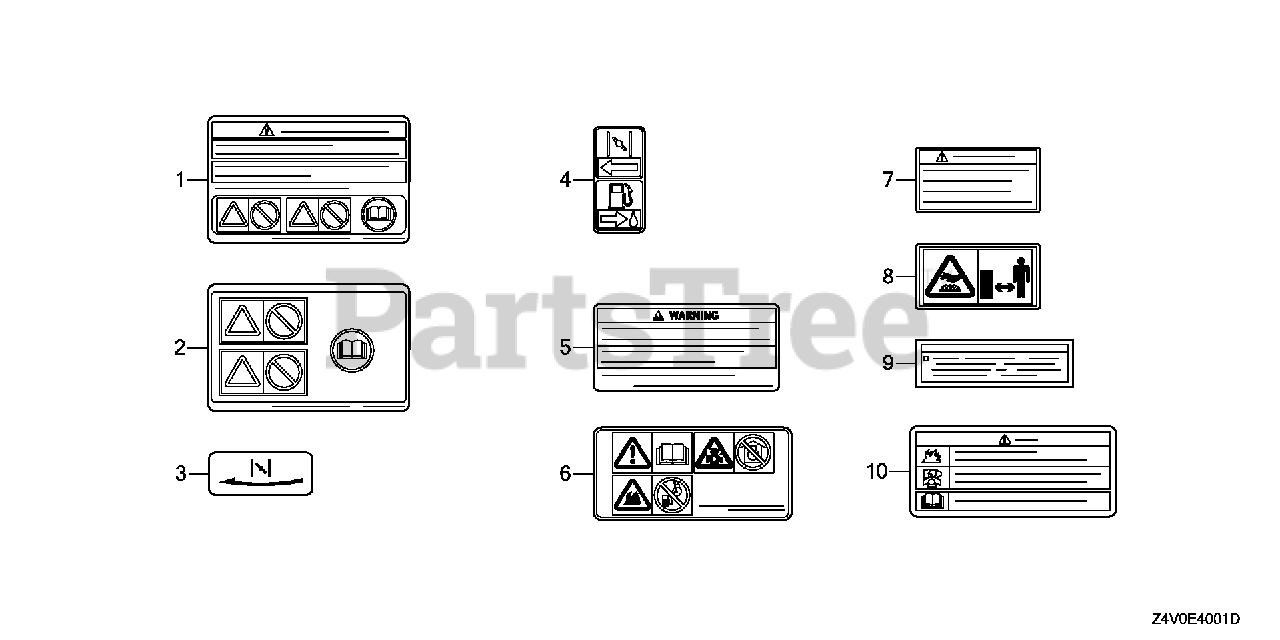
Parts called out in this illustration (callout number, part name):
1	MARK, OPERATOR CAUTION (FRENCH)(MADE IN THAI)
5	MARK, OPERATOR CAUTION (ENGLISH)(MADE IN THAI)
5	MARK, OPERATOR CAUTION (FRENCH)(MADE IN THAI)
7	MARK, EX. CAUTION (ENGLISH)
7	MARK, EX. CAUTION (FRENCH)
